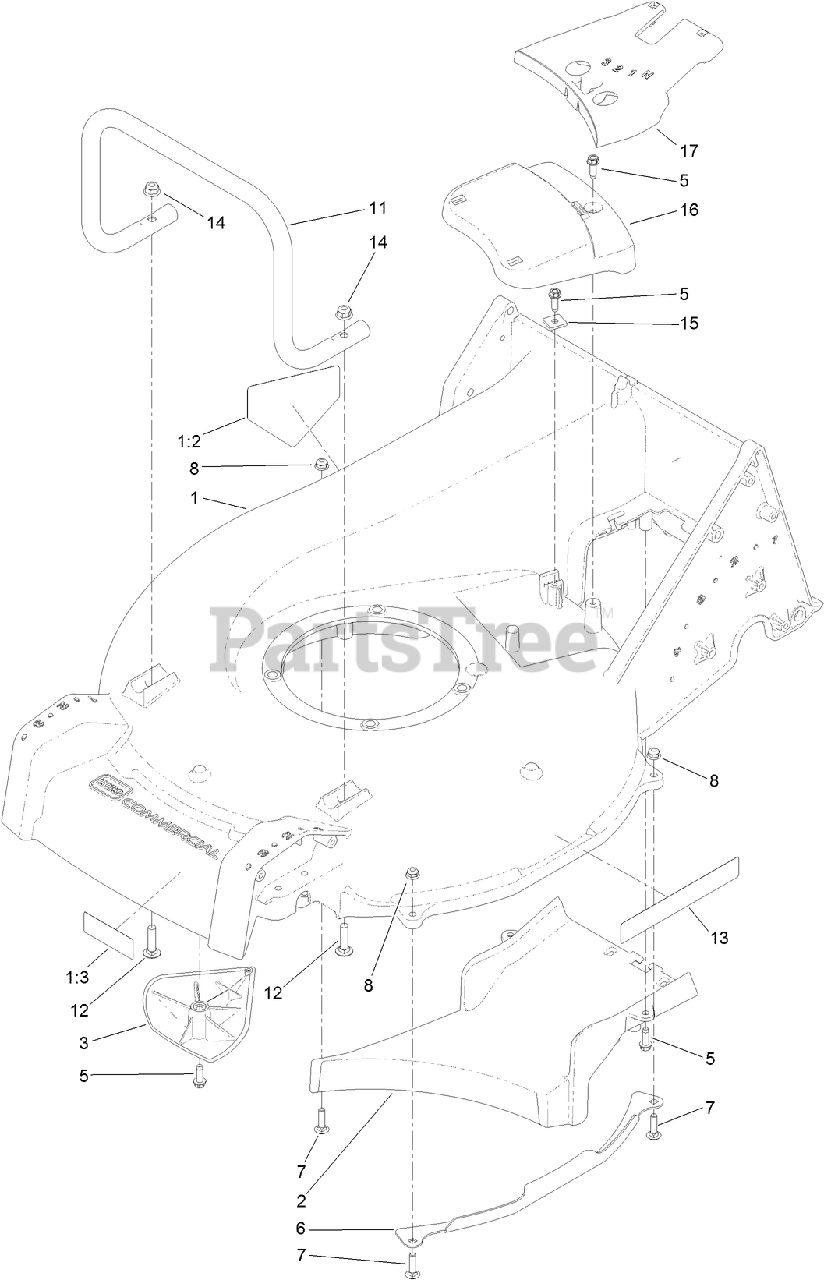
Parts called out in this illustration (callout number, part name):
1	HOUSING ASM
1:2	DECAL-DANGER
1:3	DECAL-BLADE
2	FLOOR-CHUTE
3	KICKER
5	SCREW-HWHTF
6	GUARD-SIDE, DECK
7	SCREW-CARR
8	NUT-HF
11	GUARD-ENGINE
12	SCREW-CARR
13	DECAL-RECYCLER
14	NUT-HF, NI
15	CLAMP-CABLE
16	COVER-BELT, FRONT
17	COVER-BELT, REAR
